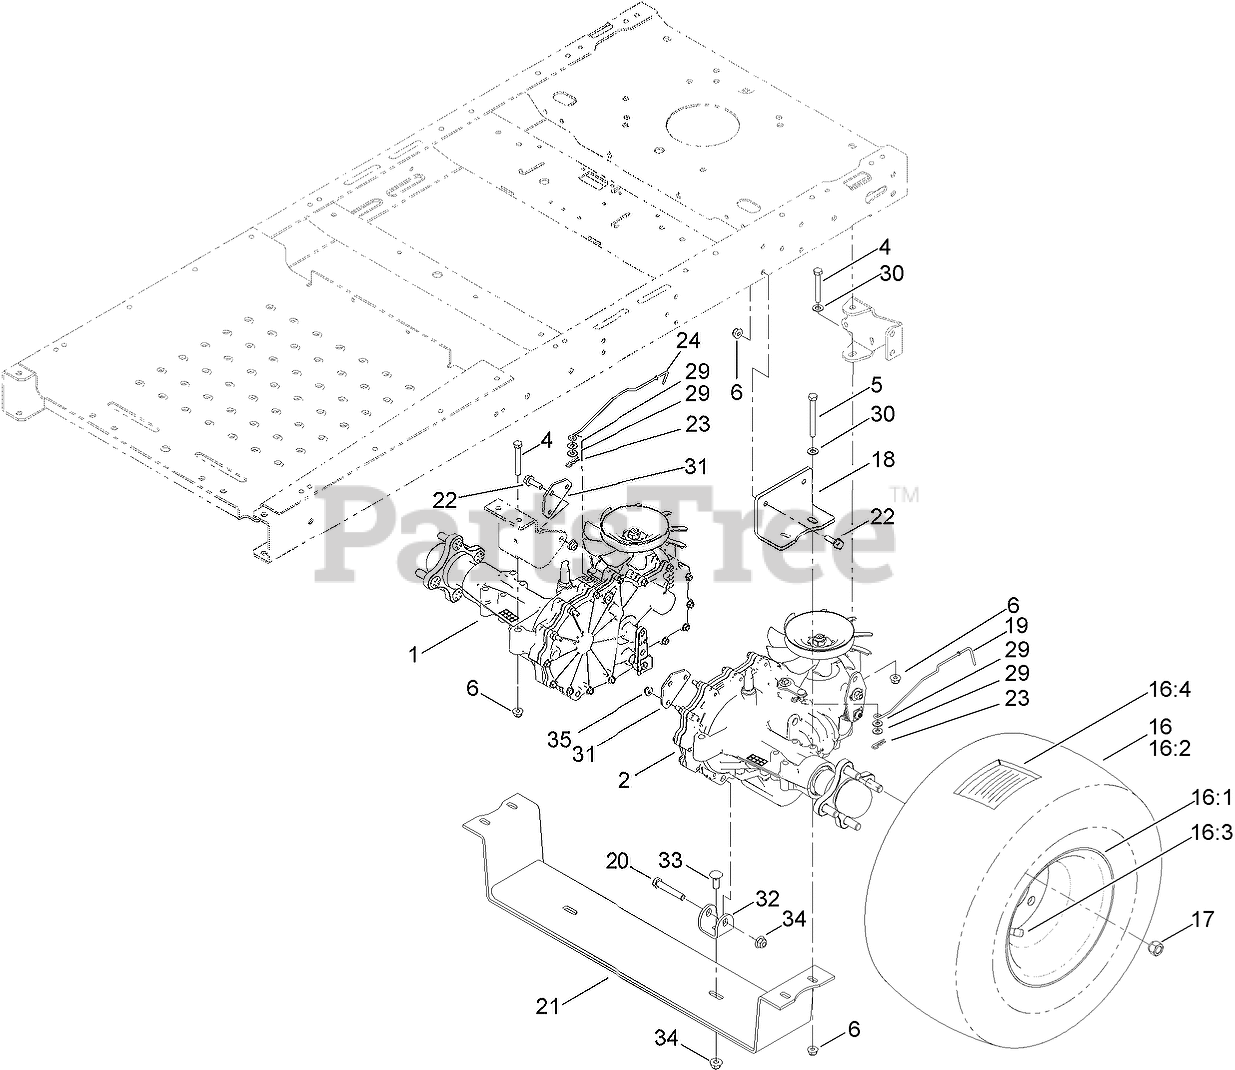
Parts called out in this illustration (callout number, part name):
1	RH HYDRO TRANSAXLE ASM
2	LH HYDRO TRANSAXLE ASM
4	SCREW-HH
5	SCREW-HH
6	NUT-HF, NI
16	4 PLY WHEEL AND TIRE ASM
16:2	TIRE-4 PLY
16:3	STEM-VALVE
16:4	TUBE-INNER
17	NUT-LUG
18	MOUNT-HYDRO
19	ROD-BYPASS, LH
20	SCREW-HH
21	MOUNT-HYDRO
22	SCREW-HHF
23	PIN-COTTER
24	ROD-BYPASS, RH
29	WASHER-FLAT
30	WASHER-PLAIN
31	PLATE-HYDRO MOUNT
32	TAB-HYDRO
33	BOLT-CARR
34	NUT-HF, NI
35	NUT-HF
